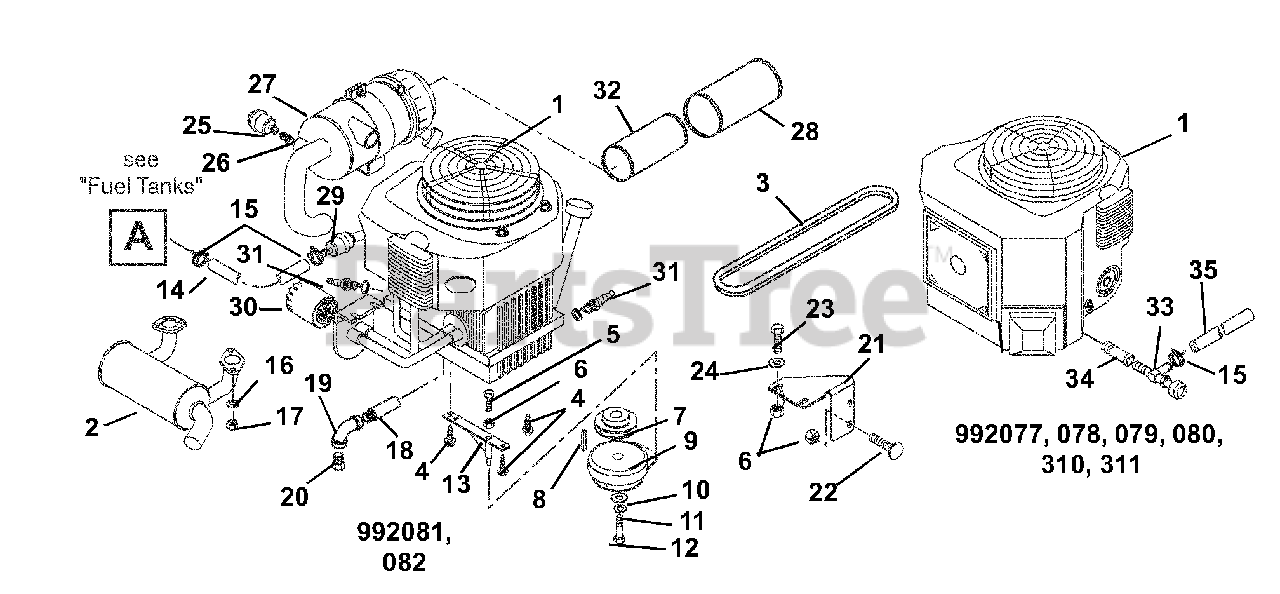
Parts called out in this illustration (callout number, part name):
1	Engine, Kohler, 25HP (081, 082)
1	Engine, Kawasaki 19HP (077, 310)
1	Engine, Kawasaki 21HP (078, 311)
1	Engine, Kawasaki 23HP (079, 080)
2	Muffler, Kohler (081, 082)
2	Muffler, Kawasaki (077, 078, 079, 080, 310, 311)
3	V-Belt HA 52 x .535 G48667
4	Screw, Tapping Hex Washer Head .38-16 x 1.00 (077, 078, 079, 080, 310, 311)
4	Screw, Tapping Hex Washer Head .38-16 x 1.00 (081, 082)
5	Bolt, Hex .31-18 x 1.50 Grade 5 (077, 078, 079, 080, 310, 311)
6	Nut, Locking Top Flange .31-18 (081, 082)
6	Nut, Locking Top Flange .31-18 (077, 078, 079, 080, 310, 311)
7	Pulley-V 4.00 x 1.125 with Key 1.42 Height
8	Key, Square .25 x .625 x .25 SAE 8630 OR SAE 1035
9	Clutch, Electric
10	Washer, Flat Steel .515 x 1.625 x .25
11	Washer, Locking .44 x .109
12	Bolt, Hex .44-20 x 2.50 Grade 5
13	Weldment, Clutch Anchor
14	Gas Line, Bulk .25 ID
15	Hose, Clamp
16	Washer, Lock .31 x .078 Regular
17	Nut, Hex M8-1.25
18	Nipple (081, 082)
19	Elbow .375-18 (081, 082)
20	Pipe Plug (081, 082)
21	Bracket, Oil Filter Mounting-Kohler (081, 082)
22	Bolt, Round Head Square Neck .31-18 x .62 (081, 082)
23	Bolt, Hex .31-18 x 1.00 Grade 5 (081, 082)
24	Washer, Flat Steel .38 x .875 x .083 (081, 082)
25	Filter Minder (081, 082)
26	Nipple, .125 NPT (081, 082)
27	Assembly, Air Cleaner
28	Filter, Outer Element
29	Fuel Filter, Kohler (081, 082)
29	Fuel Filter, Kawasaki (077, 078, 079, 080, 310, 311)
30	Oil Filter, Kohler (081, 082)
30	Oil Filter, Kawasaki (077, 078, 079, 080, 310, 311)
31	Spark Plug, Kohler (081, 082)
31	Spark Plug, Kawasaki (077, 078, 079, 080, 310, 311)
32	Filter, Inner Element
33	Cock, Oil Drain (077, 078, 079, 310, 311)
34	Adapter, Oil Drain (077, 078, 079, 310, 311)
35	Gas Line, Bulk .25" ID (077, 078, 079, 310, 311)
